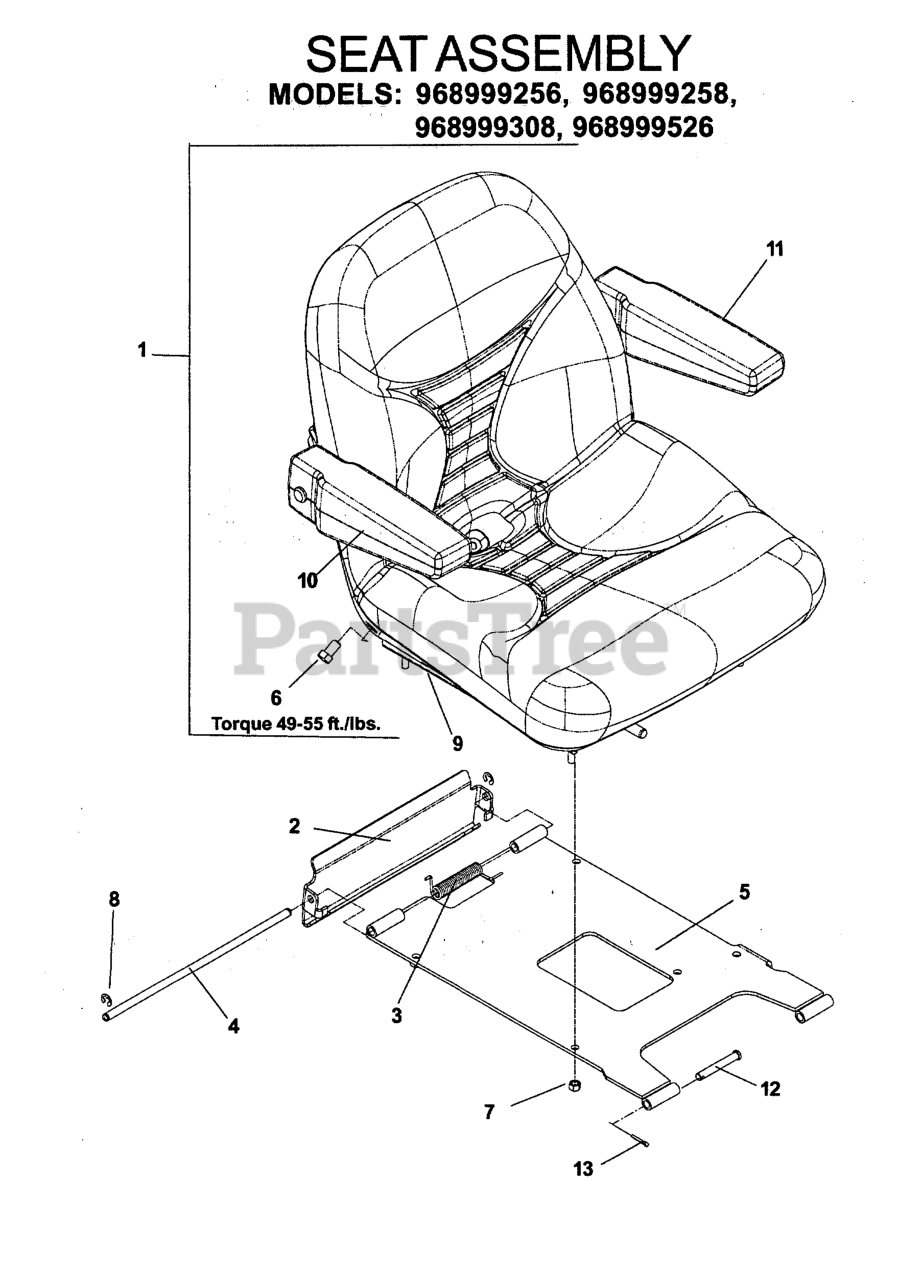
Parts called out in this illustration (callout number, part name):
1	SEAT KIT
2	SEAT LATCH BRACKET
3	TORSION SPRING (SEAT)
4	SEAT LATCH ROD
5	SEAT MOUNTED WLDMT
6	HCS 7/16-20 X .75 GD 5
7	NUT 5/16 NYLOC
8	E RING 3/8"
9	TRACK ADJUSTMENT KIT
10	ARMREST KIT, RT SQUARE END
11	ARMREST KIT, LT SQUARE END
12	CLEVIS PIN 3/8
13	RP_COTTER PIN 1/8 X 3/4
